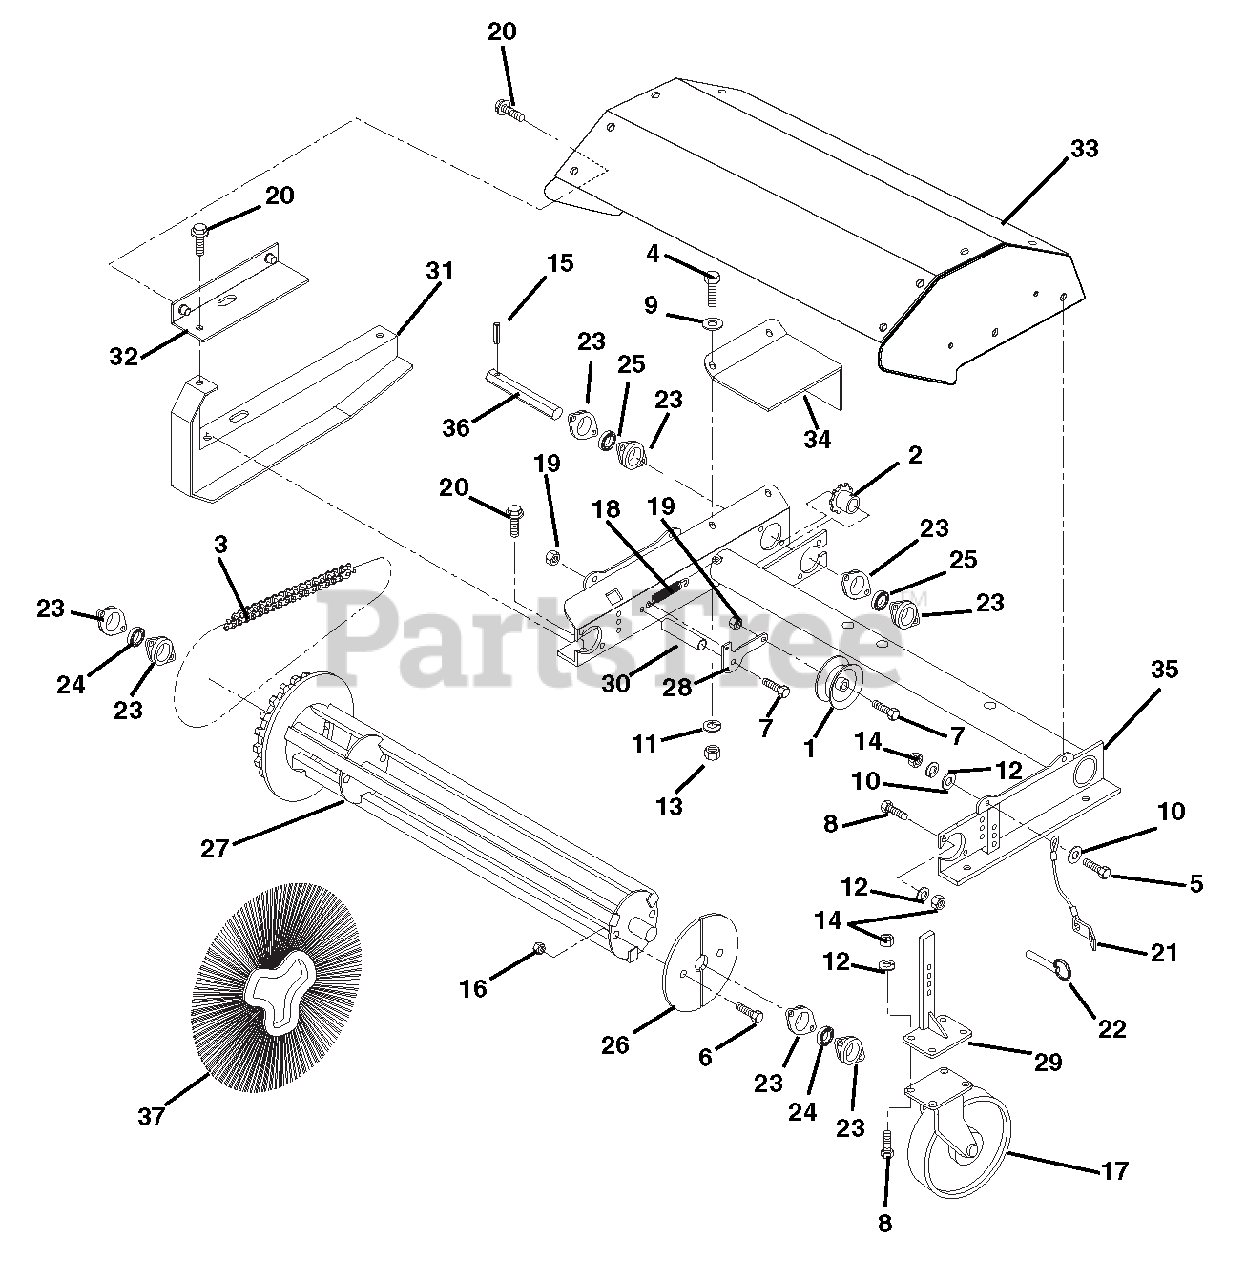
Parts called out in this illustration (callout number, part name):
1	CHAIN TIGHTENER
2	SPROCKET
3	CHAIN, ASS'Y #40X106 EDLS W/LK
4	@BLT-HEX .25-20X.75 GR5 YWZC
5	@BLT-HEX .31-18X1.00 GR5 YWZC
6	@BLT-HEX .31-18X2.25 GR5 YWZC
7	@BLT-HEX .38-16X1.50 GR5 YWZC
8	@BLT-HEX .31-18X.75 GR5 YWZC
9	@WSHR-FL-STL.281X.62X.065 YWZC
10	@WSHR-FL-STL.312X.734X.065 YWZ
11	@WSHR-LK .25X.062 REG YWZC
12	@WSHR-LK .31X.078 REG YWZC
13	@NUT-HEX .25-20 YWZC
14	@NUT-HEX .31-18 YWZC
15	PIN, SPRING LOK .187 X 1.25
16	NUT, LOK STAMPED .312-18 TINN.
17	WHL, 5 DIA.
18	SPRING, TENSION .50 X 3.0
19	@NUT-LK-CTR .38-16 YWZC
20	SCREW, GR 10.9 M6X1-20
21	LANYARD,.06 CAB.1.25X6,TYP C
22	PIN, HITCH, .38 X 2
23	FLANGE, SPHERICAL 2"
24	BRG 1.00 BORE, SPHER. OD.
25	BRG-BALL .884HEXX52MMX1.07
26	RETAINER PLATE (SET OF 2)
27	WELD, CORE C36TW
28	ARM, IDLER,BRM C36TW
29	WELD, CASTER LEG, C36TW
30	BSHG, .62X12 GA X.75
31	SHIELD,CHAIN, ARIENS
32	SHIELD, CHAIN,TOP,ARIENS
33	KIT, HD, ARIENS
34	SHIELD, INPUT, ARIENS
35	WELD, BFRM,ARIENS
36	SHAFT, HEX 20.1", W/HOLE
37	SET,SECTION,24",P,CONV.
